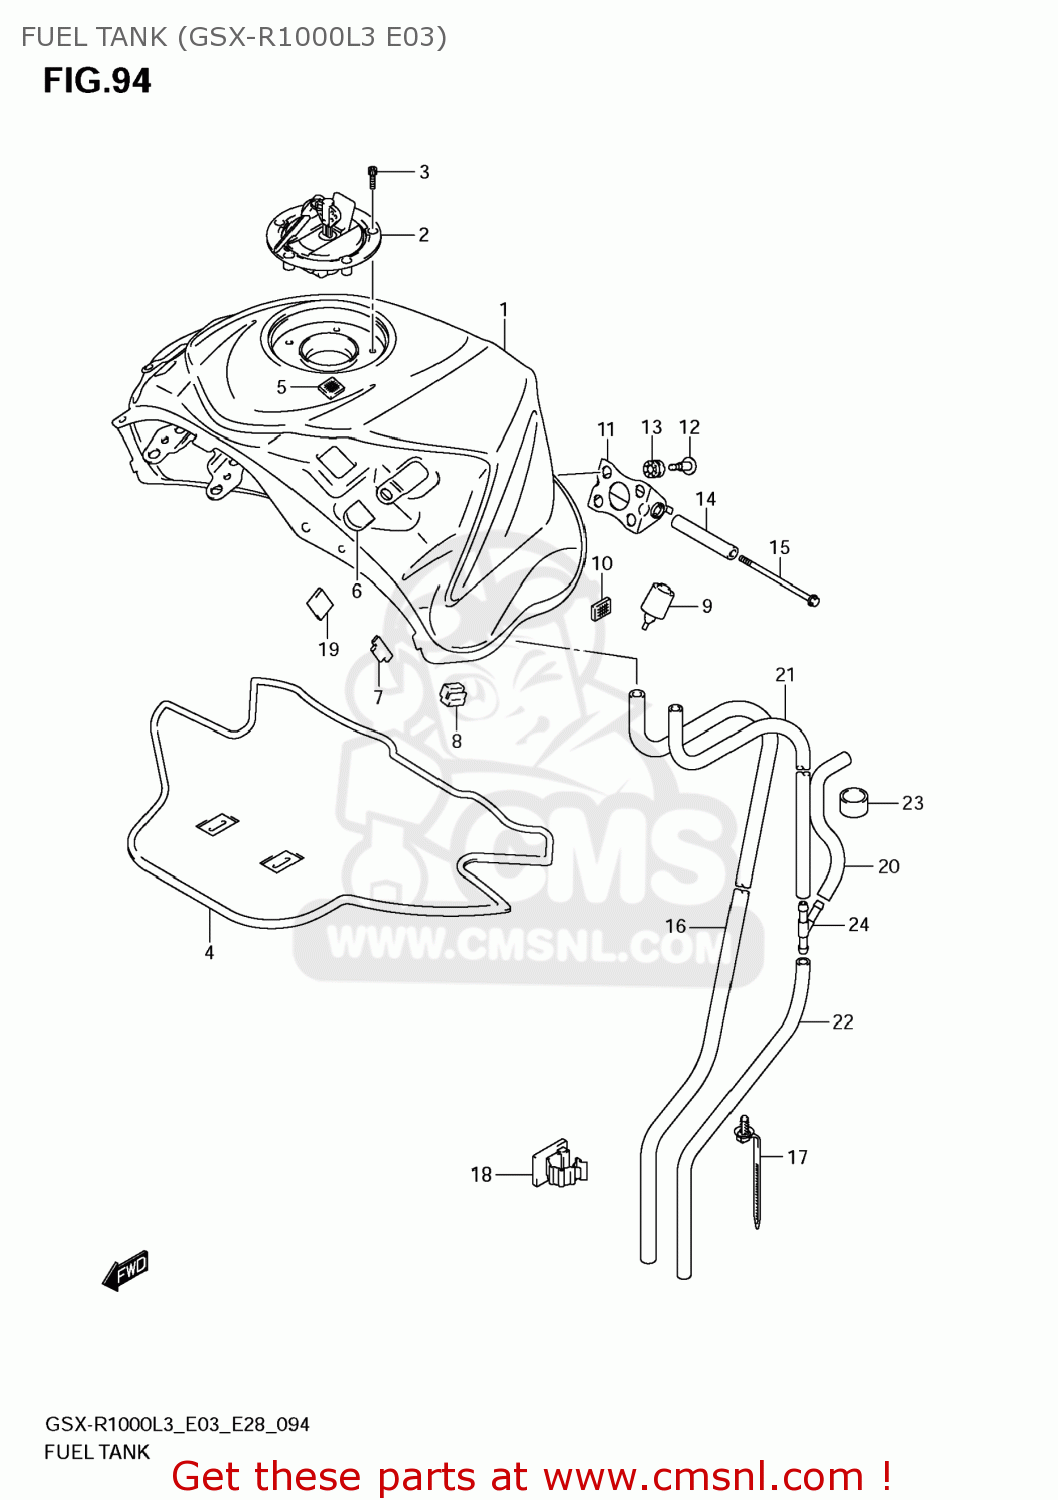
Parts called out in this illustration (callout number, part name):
1	TANK ASSY,FUEL(BLUE)
2	CAP SET,FUEL TANK
3	BOLT(5X20)
4	SHIELD,FUEL TANK HEAT
5	FASTENER
6	CUSHION
7	CUSHION,FUEL TANK COVER
8	CUSHION,FUEL TANK SIDE
9	CUSHION,FUEL TANK RR
10	FASTENER
11	BRACKET,FUEL TANK NO.1
12	SCREW(6X22)
13	CUSHION
14	SPACER,FUEL TANK RR
15	BOLT(6X110)
16	HOSE,FUEL TANK WATER DRAIN
17	CLAMP(L:154)
18	CLAMP
19	PAD
20	HOSE,TANK BREATHER NO.2
21	HOSE,FUEL TANK BREATHER NO.1
22	HOSE,FUEL TANK BREATHER NO.2
23	HOSE(12X16X600)
24	3 WAY
